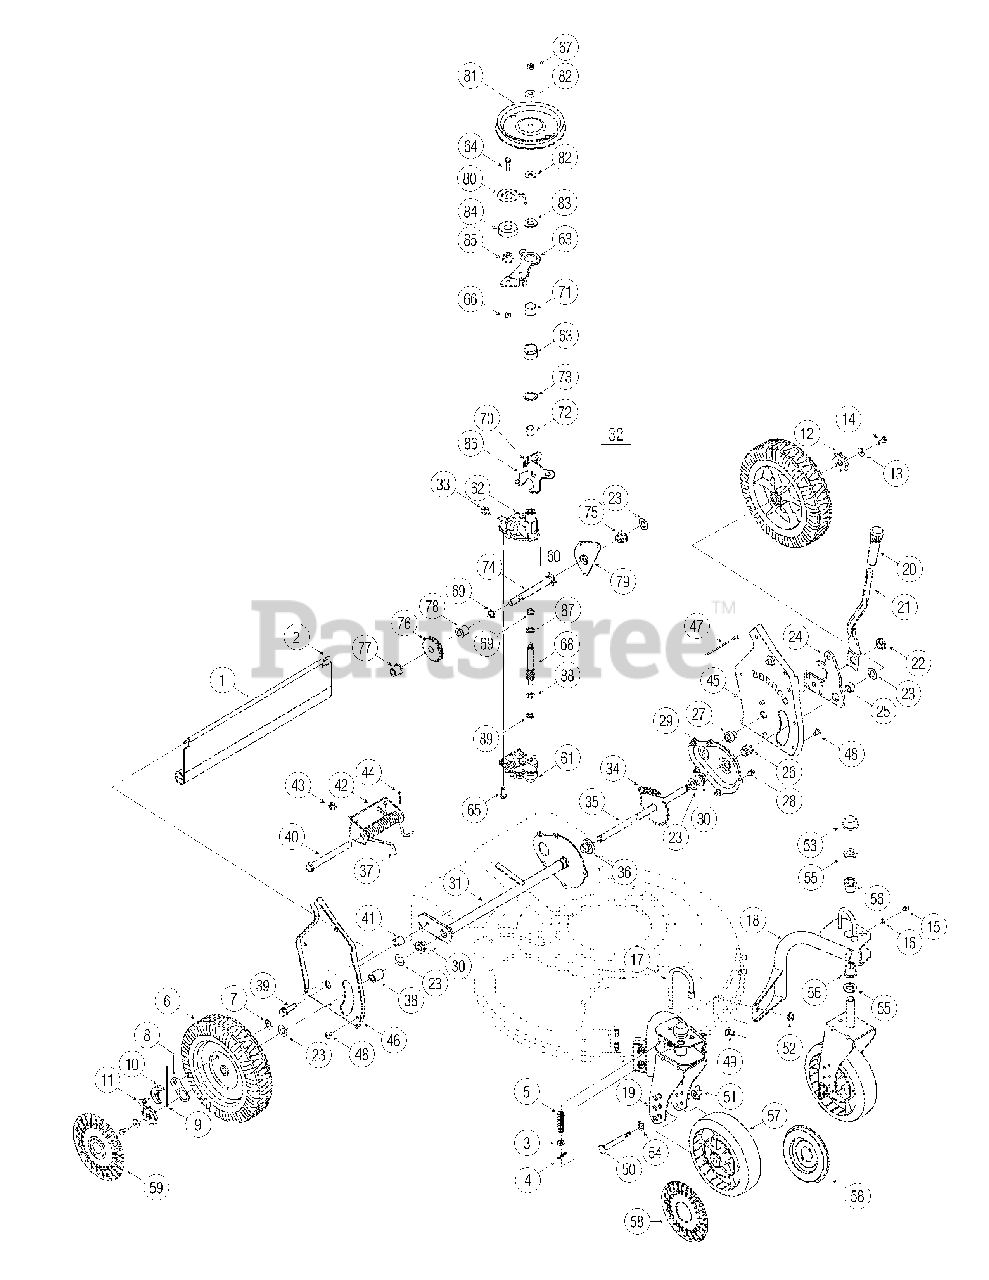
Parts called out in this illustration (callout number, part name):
1	Trail Shield
2	Trail Shield Wire
3	Flat Washer.330 ID x.630 OD
4	Cotter Pin
5	Compression Spring
6	Wheel 9 x 2
7	Top Lock Tab Weld Nut 1/4-20
8	Ratchet Pawl Plate
9	Plastic Spring Ratchet
10	Pawl RH
10	Pawl LH
11	Shoulder Screw.340 ID x.285 OD
12	Wheel Ratchet
13	Bell Washer.265 ID x.75 OD
14	Hex Cap Screw 1/4-20 x.620
15	Grease Fitting
16	Flat Washer.203 ID x.403 OD
17	Wheel Pin Lock
21	Spring Lever
22	Shoulder Nut.825 x .165 Lg.
23	Flat Washer .508 ID x 1.0 OD
24	Pivot Arm Assembly
25	Spacer .510 ID x .70 OD
26	Sleeve Bearing .504 ID x .830 OD
27	Shoulder Spacer
28	Tap Screw 1/4-20 x .375
29	Chain Cover Assembly
30	Flange Bearing .506 ID x .590 Lg
31	Transmission Axle Assembly
32	Transmission Assembly Complete
33	Hex Screw 5/16-18
34	Chain
35	Rear Axle Assembly
36	Flange Bearing .506 ID x .715 Lg
37	Torsion Spring
38	Spacer .550 ID x .750 OD
39	Screw 3/8-16 x .25
40	Clevis Pin .50 Dia x 4.82 Lg.
41	Spacer .385 ID x .624 OD
42	Spring Bracket: Height Adjustment
43	Screw 1/4-14 x .825
44	Cotter Pin
48	Screw 1/4-14 x.500
49	Carriage Bolt 5/16-18 x.62
50	Caster Axle
51	Wing Nut
52	Flange Lock Nut 5/16-18
53	Push Cap
54	Wave Washer.531 ID x.781 OD
55	Flat Washer.640 ID x 1.12 OD
56	Flange Bearing
57	Wheel 7 x 2
58	Hubcap - Spoke w/ Hole
59	Hubcap - Radial Spoke
60	Shaft Assembly
61	Lower Housing Assembly
62	Upper Housing Assembly
63	Idler Bracket Assembly
64	Hex Cap Screw 1/4-28 x 1.0
65	Hex Screw 1/2-20 x .75
66	Hex Jam Nut 1/4-28
67	Hex Jam Nut 5/16-24
68	Pinion Shaft 10T
69	Oil Seal
70	Extension Spring
71	Bearing Sleeve
72	Bearing
73	Thrust Washer .504 ID x .70 OD
74	Output Shaft 6T
75	Flange Bearing
76	Gear 34T
77	Flange Bearing
78	Flange Bearing
79	Pivot Bracket
80	Belt Keeper
81	Pulley
82	Bell Washer .325 ID x .930 OD
83	Flat Washer .510 ID x 1.120 OD
84	Bearing
85	Flange Spacer
86	Cable Bracket
87	Flat Washer .885 ID x 1.45 OD
88	Thrust Washer .388 x .625
89	Thrust Washer 3/8 x .70
